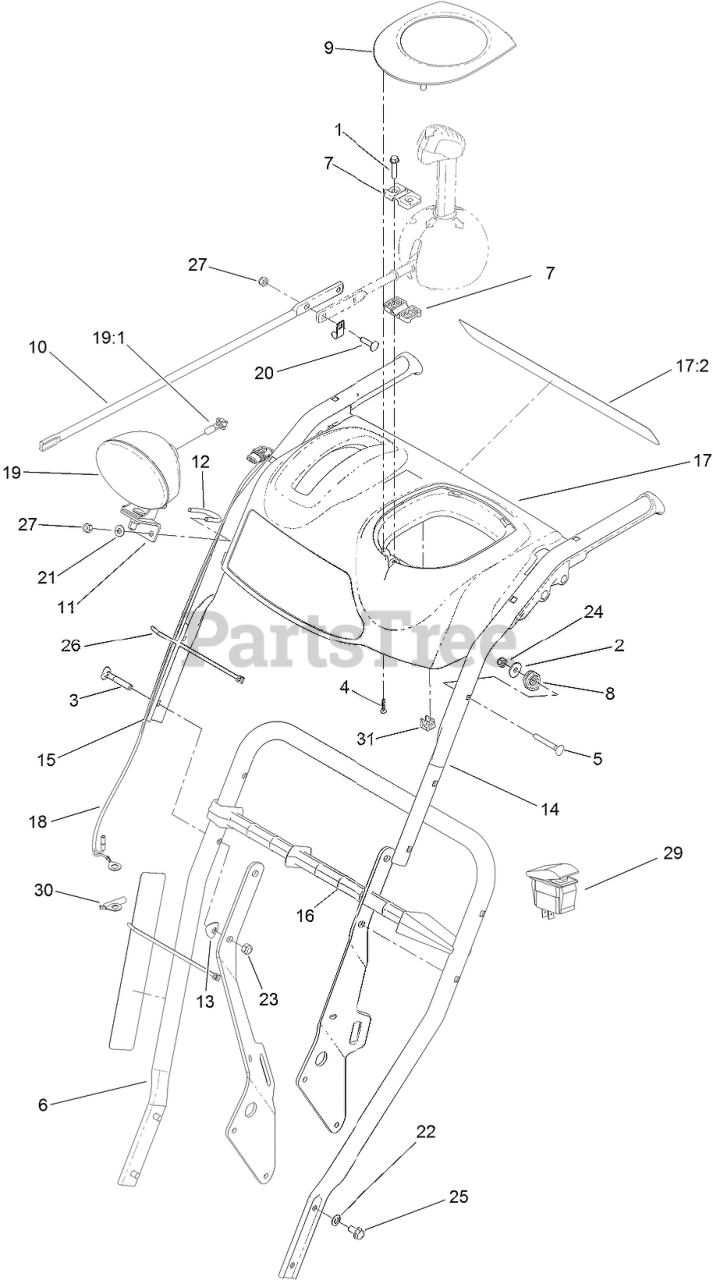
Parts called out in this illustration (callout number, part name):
1	SCREW-PLASTITE, HWH
2	WASHER-PLAIN
3	SCREW-HANDLE
4	SCREW-PPH
5	BOLT-CARR
6	HANDLE-LOWER
7	SUPPORT-ROD
8	CLAMP-CABLE
9	COVER-PANEL, CONTROL
10	ROD-CHUTE, FRONT
11	BRACKET-LIGHT
12	CLAMP-LIGHT
13	WASHER-CUP
14	HANDLE-UPPER, LH
15	HANDLE-UPPER, RH
16	STICK-CLEANOUT
17	CONTROL PANEL ASM
17:2	DECAL-CONTROL
18	HARNESS-WIRE, HEATED GRIPS
19	HEADLAMP ASM
19:1	LAMP-12 VOLT
20	BOLT-CARR
21	WASHER-PLAIN
22	WASHER-BELLEVILLE
23	NUT-HEX
24	NUT-HEX
25	SCREW-HWHTF
26	TIE-CABLE
27	NUT-HEX
29	SWITCH-ROCKER, OFF-NONE-ON
30	HARNESS-WIRE, GROUND JUMPER
31	CLIP-EDGE
